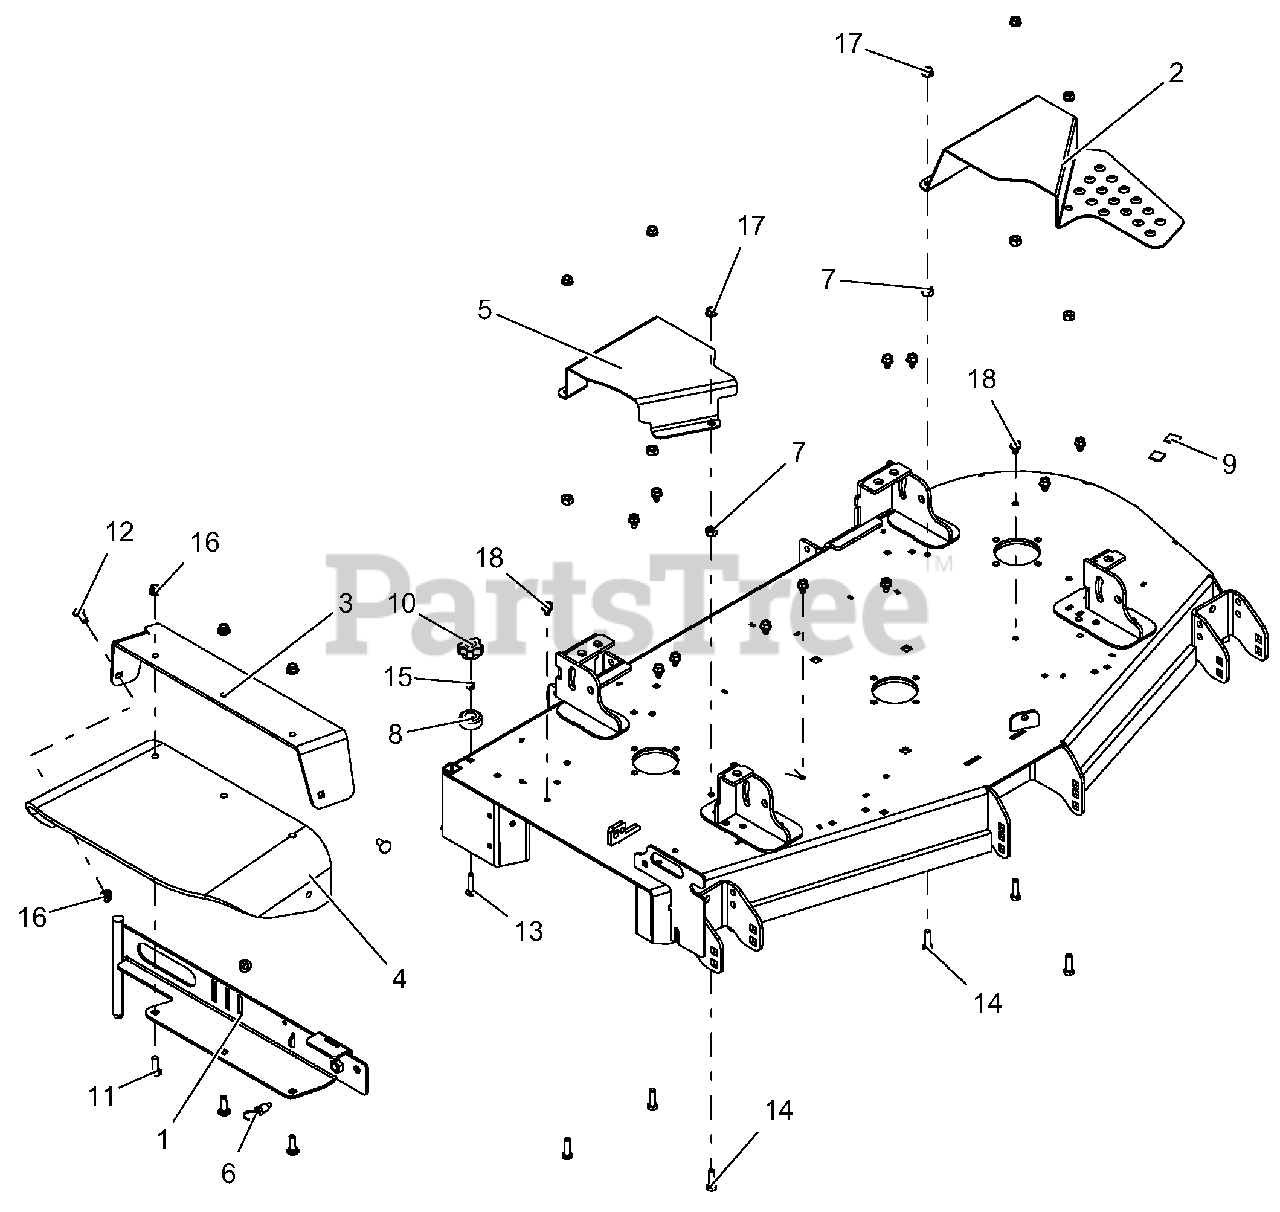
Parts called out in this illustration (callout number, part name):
1	WLDMT, 52"-60" DISCH CHUTE MTG-RED
2	GUARD, 52" LH DECK BELT
3	DISCHARGE CHUTE SUPPORT W/SAFETY DECAL-RED
4	CHUTE, RUBBER DISCHARGE
5	GUARD, 48"-52" RH DECK BELT-RED
6	PULL PIN,.50-13THDX.310 PLNGR
7	NUT-HEAVY HEX .38-16 YWZC
8	BUMPER, RECESSED 1.50 X .63 W/.31 HOLE
10	KNOB, CLAMPING
11	BLT-RDHDSQNK .38-16X1.25 G5 YWZC
12	BLT-RDHDSQNK .38-16X1.00 G5 YWZC
13	BLT-RDHDSQNK .31-18X1.50 G5 YWZC
14	BLT-HEX .38-16X1.25 GR5 YWZC
15	NUT-LK-CTR .31-18 YWZC
16	NUT-LK-NYL-FLG .38-16 YWZC
17	@NUT-SPNLK-FLG .375-16 YWZC
18	SCR-TAP .38-16X.50 HWH TR YWZ
